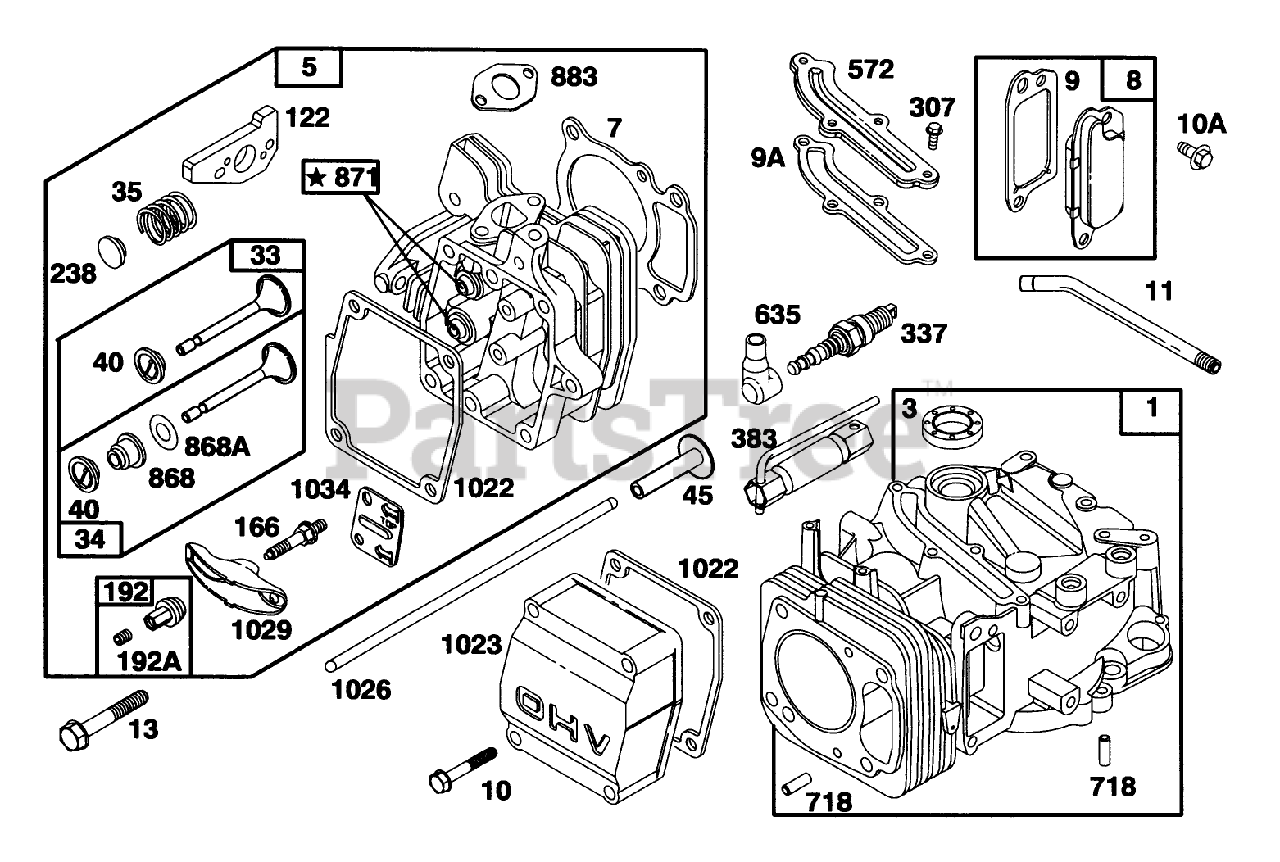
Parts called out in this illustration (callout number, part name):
98A	SPEED ADJUST. SCREW ASM
163	AIR CLEANER GASKET
188	SCREW - HEX HEAD
201	GOVERNOR LINK
209	GOVERNOR SPRING
529	TUBE - BREATHER
535	FILTER ELEMENT
618	RETURN SPRING
620	CARBURETOR BRACKET
621	STOP SWITCH
966	AIR CLEANER BASE
968	AIR CLEANER COVER
969	AIR CLEANER SCREW
971	AIR CLEANER SCREW
